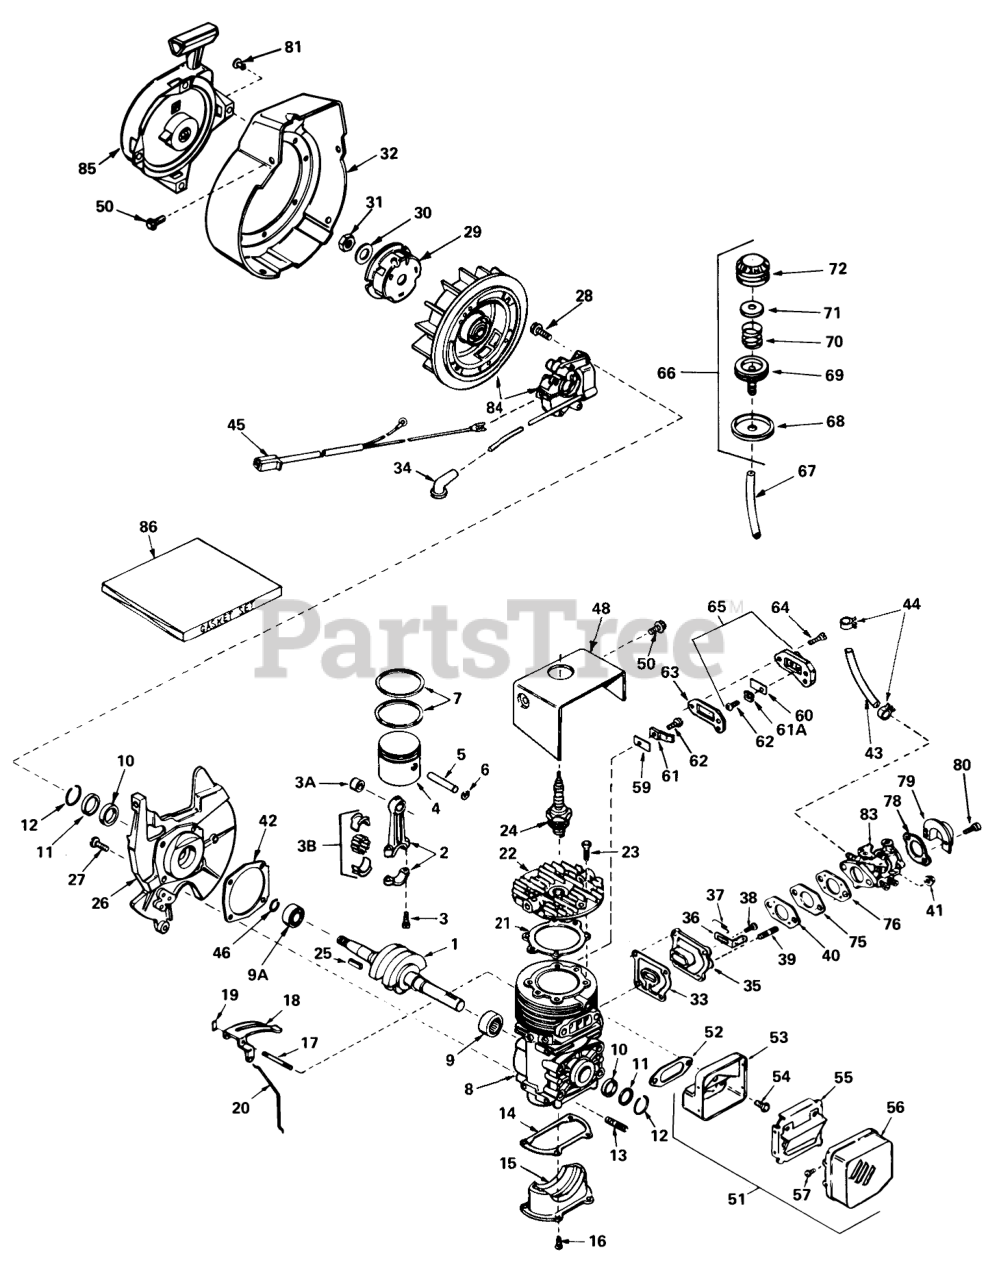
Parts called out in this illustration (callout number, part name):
1	Crankshaft
2	Rod Assy., Connecting (Incl. Nos. 3, 3A & 3B
3	Bolt-Rod, Connecting
3A	Bearing-Cartridge
3B	Bearing & Liner Set Needle
4	Piston
5	Pin, Piston
6	Ring-Retaning
7	Ring Set
8	Block Assy., Cylinder (Incl. Nos. 9, 10 thru 13, 17 & 40)
9	Bearing-Cartridge
9A	Bearing-Ball
10	Seal, Crankshaft
11	Retainer, Crankshaft Seal
12	Spring, Crankshaft Seal Retainer
14	510270 Gasket, Cover
15	Plate, Cover
16	Screw (T-25, 10-24 x 1/2)
17	Shaft, Air Vane
18	Vane Assy., Air
19	Clip,Air Vane
20	Link, Governor
21	510274 Gasket, Cylinder head
22	Support
23	Screw (T-30, 1/4-20 x 3/4)
24	Head Adjustment Knob
25	Key, Flywheel
26	Base Assy., Shroud (Incl. Nos. 10, 11 & 12)
27	Screw
28	Screw, Hex Washer Hd.
29	Starter Cup
30	Washer-Spring
31	Nut-Flywheel
32	Housing, Blower
33	510312 Gasket, Port
34	Cover-Spark Plug
35	Adapter, Cover
36	Lever, Adjusting
37	Spring, Governor
38	Screw
40	510229 Gasket, Carburetor (1/8" thick)
41	Locknut
42	510292 Gasket, Shroud base
43	Line-Fuel (8.62)
44	Clamp-Line, Fuel
45	Harness, Wire
46	Ring, Retaining
48	Shroud, Cylinder
50	Screw-Hex, Hd.
51	Muffler Assy. (Incl. Nos. 53 thru 57)
52	510230 Gasket, Exhaust
53	Base-Muffler
54	Screw
55	Baffle, Muffler
56	Cover, Muffler
59	Reed, Compression Release
60	Reed, Compression Release
61	Plate, Reed Hold Down
61A	Plate, Reed Hold Down
63	510263 Gasket, Compression release
64	Screw
65	Cover Assy., Compression release (Incl. Nos. 60, 61A & 62)
66	Primer Assy. (Incl. Nos. 68 thru 72)
67	Line, Primer
68	Retainer, Primer Bulb
69	Body Primer
70	Spring, Primer Bulb
71	Washer, Primer Bulb
72	Bulb, Primer
76	510241 Gasket, Carburetor (1/16" thick)
78	Gasket
79	Baffle-Carburetor
81	Rivet, Pop (3/16" dia.)(Can be purchased locally)
83	Carburetor (Incl. No. 76)
85	Starter-Rewind
86	Gasket Set (Incl. items marked )
